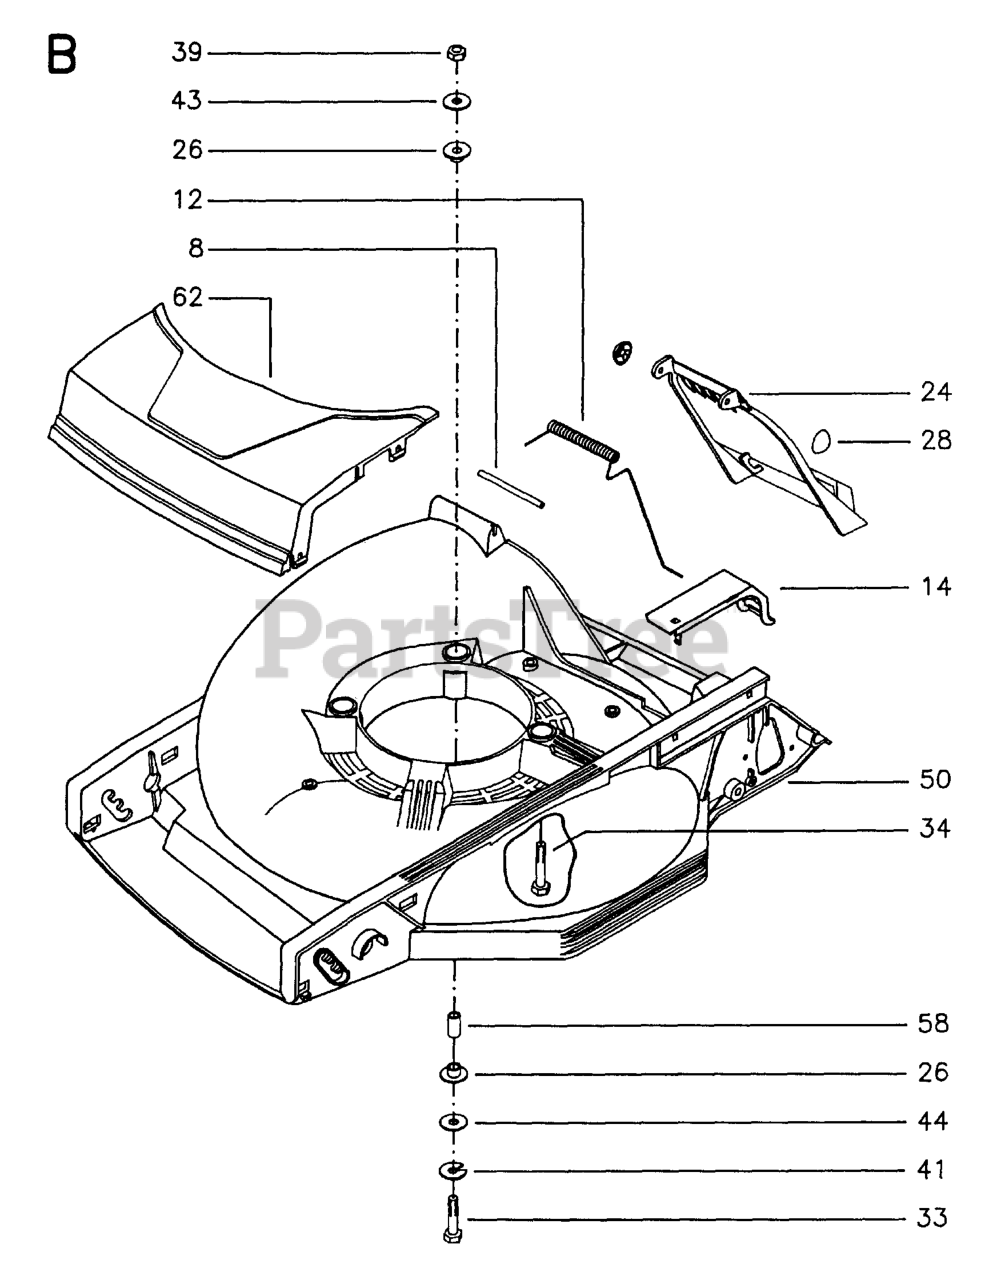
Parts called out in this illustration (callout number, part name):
8	PIN
39	LOCKNUT M8
41	SPRING WASHER
